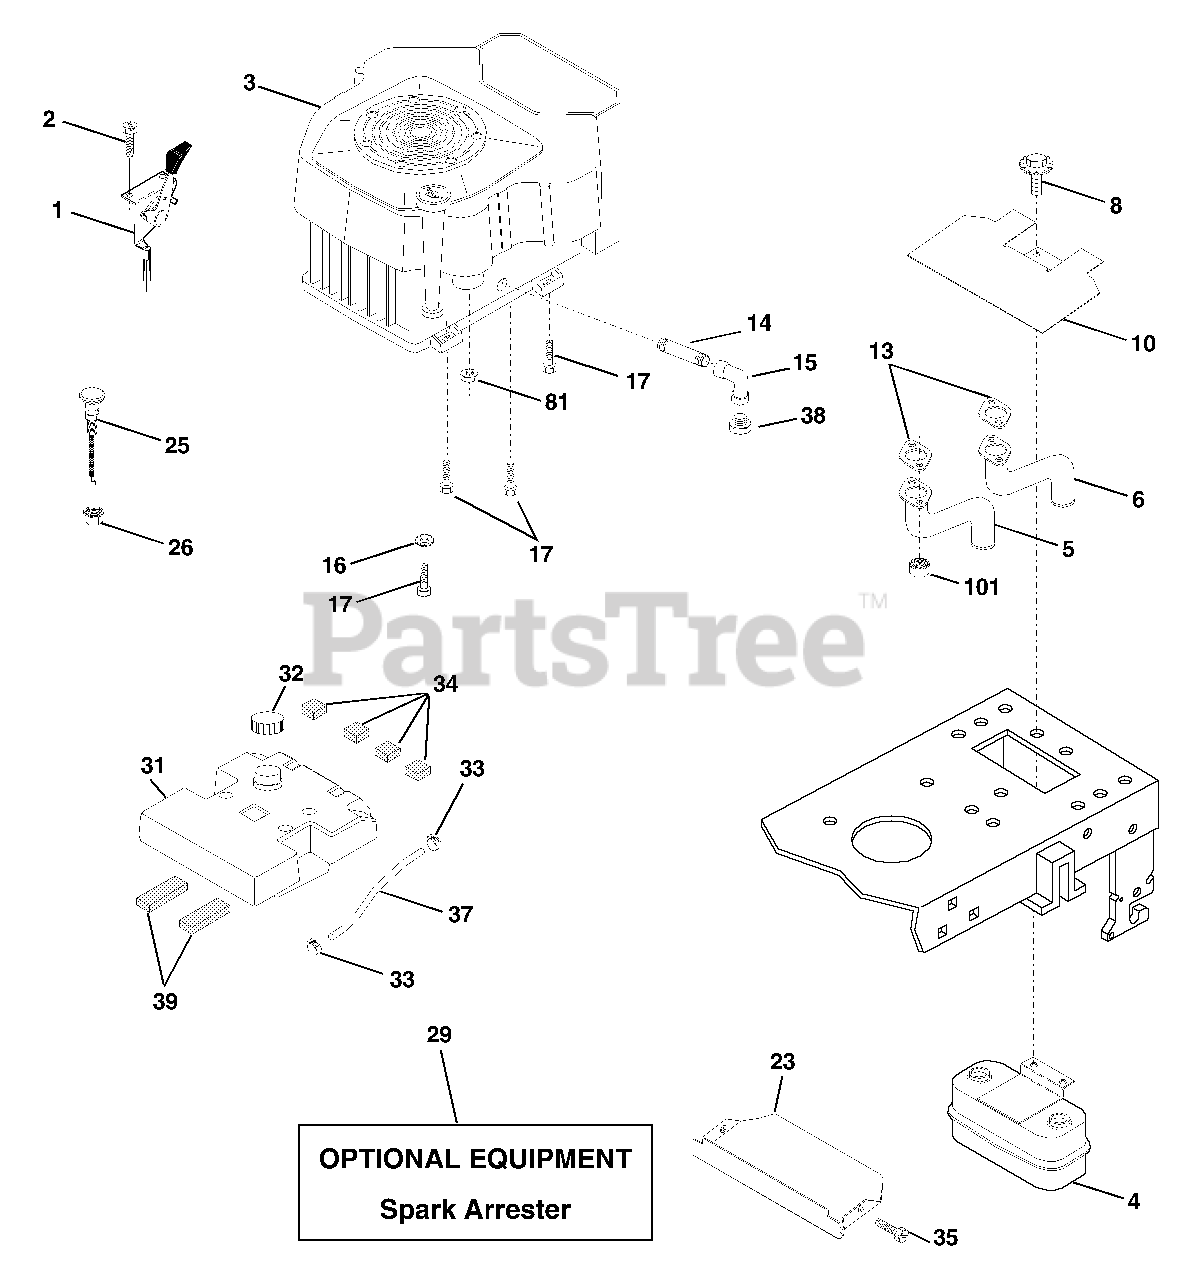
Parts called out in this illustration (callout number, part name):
1	Control Throt Flg 180 LH
2	Screw Hex Thd Cut 1/4-20x5/8 T
4	Muffler Asm Twin Lo-Tone
5	Pipe Exhaust CV18/20 LH
6	Pipe Exhaust CV18/20 RH
8	Bolt 5/16-18unc x 3/4 W/Sems
10	Shield Heat Muffler CV18/20
13	Gasket Kohler CV18-CV26
14	Nipple Pipe 3/8 Npt X 4-1/2"
15	Elbow Std 90 Degree 3/8-18 Npt
16	Washer Lock Ext Tooth 3/8
17	Screw Thdrol 3/8-16 x 1-1/2
23	Shield Browning
25	Choke Control 37"
26	Nut, Keps 3/8-24 Unf
29	Kit Spark Arrestor (Flat Scrn)
31	Tank Fuel 3 50 Rear
32	Cap Asm Fuel Top N/Lany Vented
33	Clamp Hose Blk
34	Pad, Spacer
35	Screw Thdrol 5/16-18 x 3/4
37	Line Fuel 7.5
38	Plug Oil Drain
39	Pad, Idler
81	Nut Flange 1/4-20 Starter Nut
101	Nut Flange M8-1.25 Non-Lk Zinc
